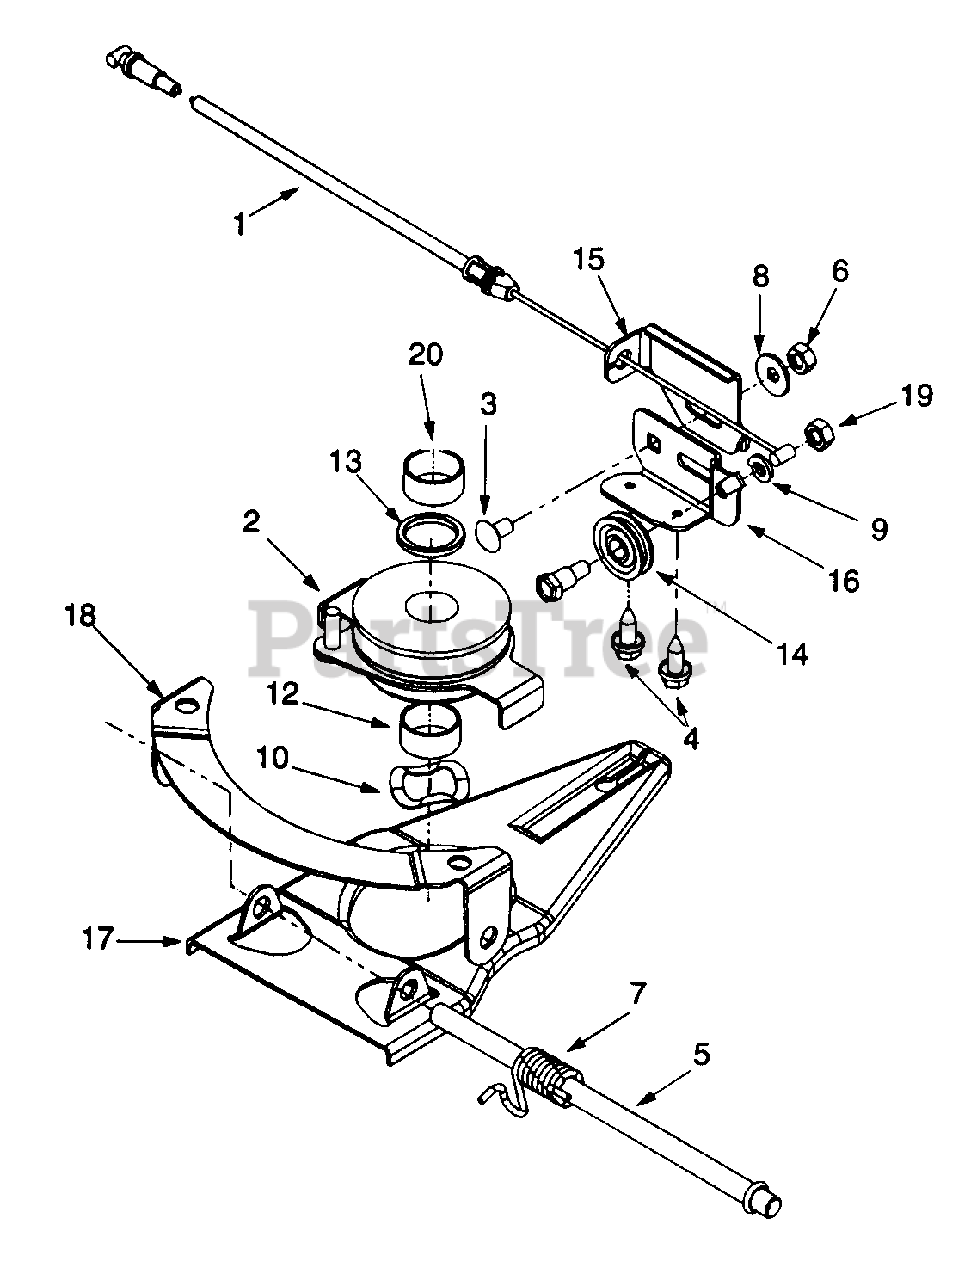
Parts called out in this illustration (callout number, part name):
1	Speed Selector Cable, 53"
2	Multi-speed Pulley Assembly
3	Carriage Bolt, 1/4-20 x .5
4	Self-tapping Screw, 1/4-20 x .625
5	Pivot Shaft
6	Nut, 1/4-20
7	LH Torsion Spring
8	Bell Washer, .265 x .75 x .062
9	Lock Washer, 1/4
10	Wave Washer, 1.38 x .88 x .029
12	Sleeve Spacer, .88 ID x 1 OD x .48
13	Sleeve Spacer, .88 ID x 1.13 OD x .12
14	Cable Roller
19	Hex Nut, 1/4-20
20	Spacer
